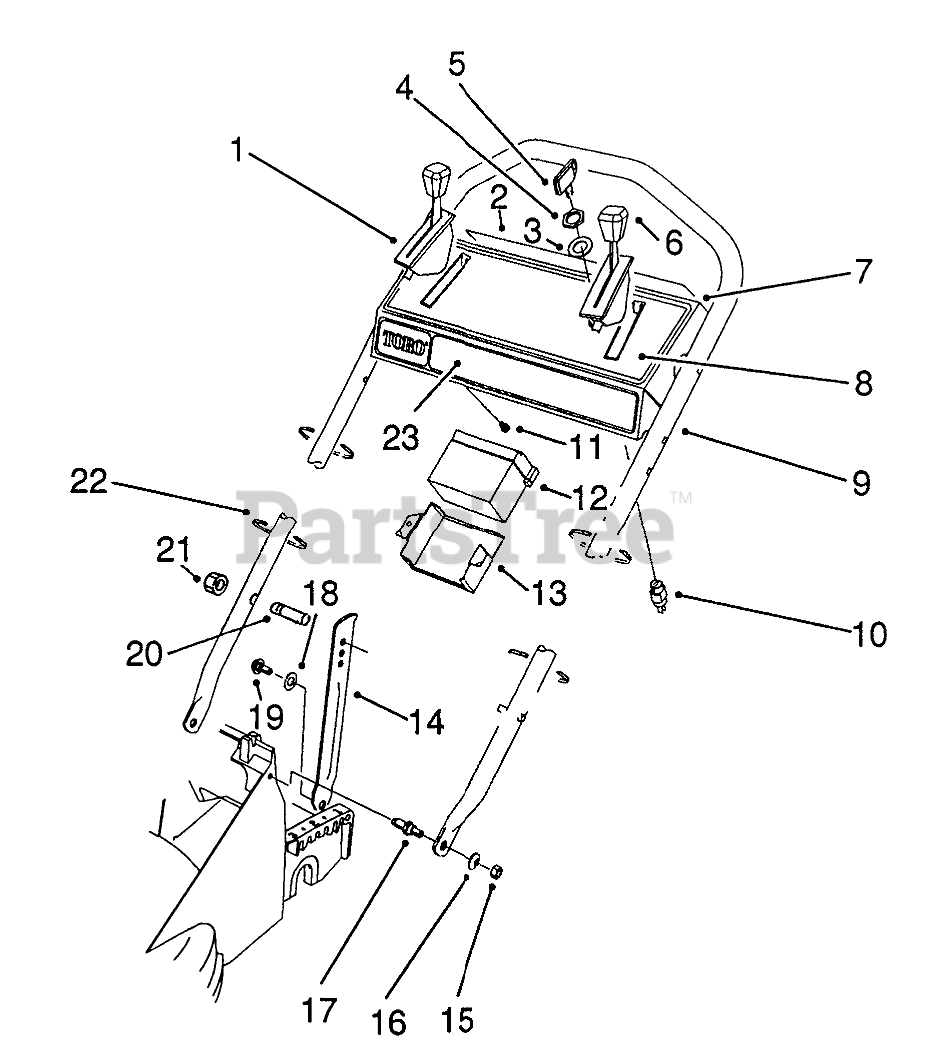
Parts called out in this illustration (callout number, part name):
1	Control-Ground Speed
2	DECAL-PANEL, DANGER
2	DECAL - PANEL, REAR
3	WASHER-TOOTH, INTERNAL
4	NUT-HH
5	KEY-IGNITION
6	ControI-Throttle Bend Type #2 Sheath Lg. 44-3/4" Wire Lg. 2-1/2"
7	Panel-Control (Incl. Ref. #8) (Model No. 26624 Only)
7	Panel-Control (Incl Ref. #8) (Model No. 26626 Only)
8	DECAL - CONTROL PANEL
8	DECAL - INSTRUCTION
9	HANDLE
10	Switch-Starter (Incl. Ref. #3-4)
11	SCREW-HWHTF
12	Retainer-Battery
13	BATTERY ASSEMBLY
14	HANDLE LATCH
15	NUT-LOCK, NI
16	WASHER-PLAIN
17	SCREW - SHOULDER STUD
18	NYLON WASHER
19	SCREW-SHOULDER
20	HANDLE PIN
21	NUT-LOCK, NI
22	TIE-CABLE
23	DECAL - KEY LECTRIC
